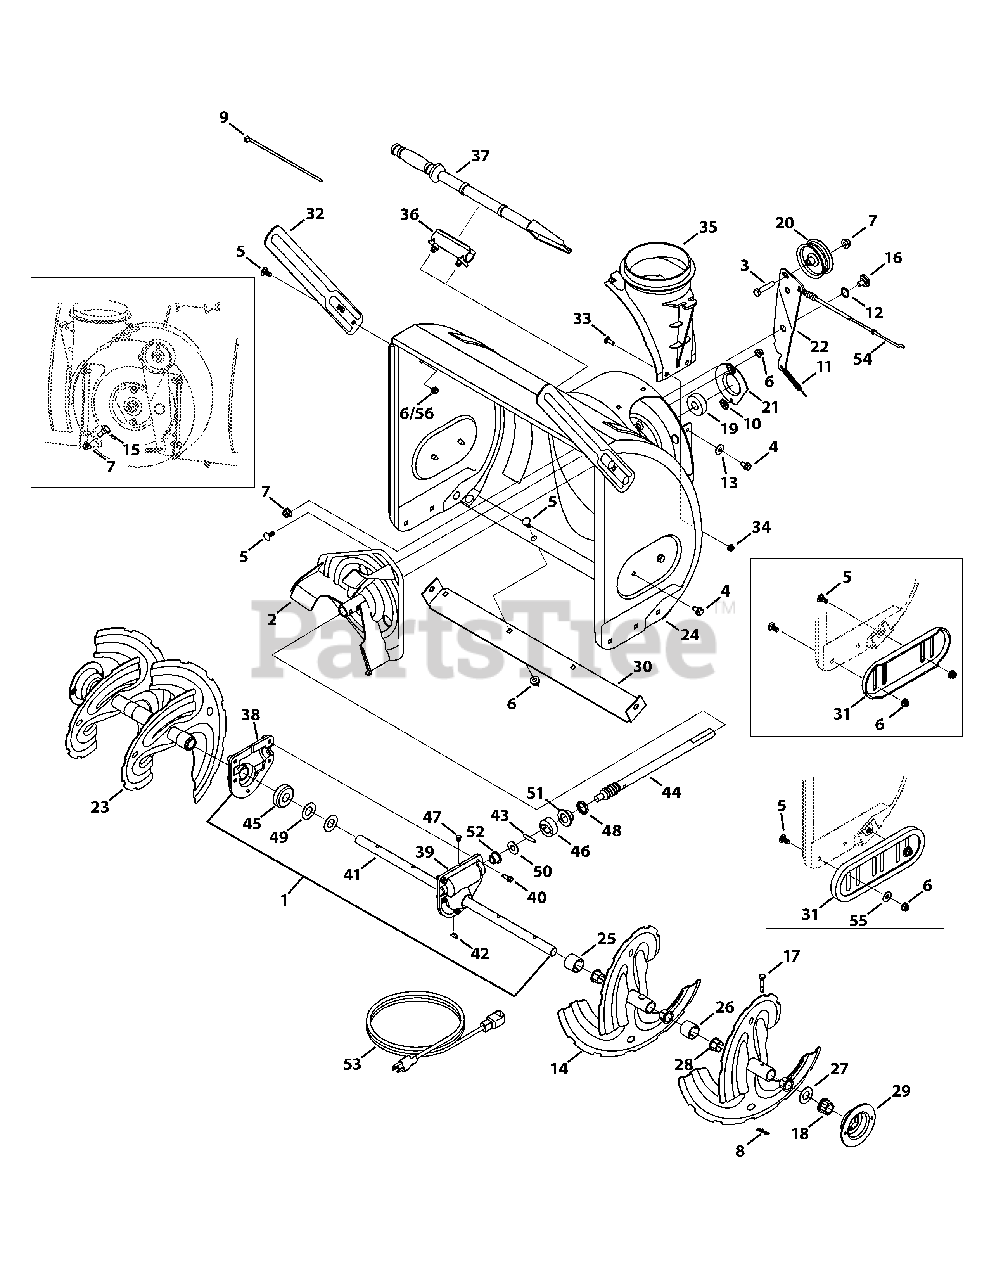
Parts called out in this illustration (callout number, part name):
1	Auger Gearbox 30", includes 38-52
1	Auger Gearbox 28", includes 38-52
1	Auger Gearbox 26", includes 38-52
1	Auger Gearbox 24", includes 38-52
2	Impeller Assembly, 12" Dia.
3	Hex Head Screw, 3/8-16 x 1.75
4	Screw, 5/16-18 x .750
5	Screw, Carriage, 5/16-18 x 1.00
6	Nut, Flange lock, 5/16-18
7	Nut, Flange lock, 3/8-16
8	Bow-Tie Cotter Pin
9	Cable Tie, 7"
10	Nut, Push-on, .25 Dia.
11	Extension Spring, .38 x 4.59
12	Washer, Wave, .625 x .885
13	Washer, Bell, .340 x .872
14	Spiral Assembly, LH - Black
14	Spiral Assembly, LH Gray
15	Bolt, Shoulder, .496 x .336 x 3/8-16
16	Screw, Shoulder, .625 x .17 x 3/8-16
17	Shear Pin, .25 x 1.50
18	Bearing, Hex Flange, .75
19	Bearing, Ball, .75 x 1.85
20	Pulley, Idler, Flat, 2.75
21	Bearing, 1.85 ID
22	Auger Idler Bracket
23	Spiral Assembly, RH - Black
23	Spiral Assembly, RH Gray
24	Auger Housing Assembly
24	Auger Housing Ass'y, 30"
24	Auger Housing Ass'y, 28"
24	Auger Housing Ass'y, 26"
24	Auger Housing Ass'y, 24"
25	Spacer, 1.25 x .75 x 1.00
26	Spacer, 1.25 x .75 x 2.00
27	Washer, Flat, .76 x 1.49
28	Bushing, Flange, .800 x .910
30	Shave Plate, 2.25 x 29.66 (30") Orange
30	Shave Plate, 2.25 x 29.66 (30") Black
30	Shave Plate, 2.25 x 27.66 (28") Orange
30	Shave Plate, 2.25 x 25.66 (26") Orange
30	Shave Plate, 2.25 x 23.66 (24") Orange
31	Reversible Slide Shoe (Steel) Black
31	Reversible Slide Shoe (Steel) Orange
31	Deluxe Polymer Reversible Slide Shoe
31	Deluxe Polymer Reversible Shoe Kit
33	Screw, Carriage, 1/4-20 x .75
34	Nut, Flange lock, 1/4-20
35	Chute Adapter
36	Clean-Out Tool Mount
37	Clean-Out Tool
38	Reducer, RH
39	Reducer, LH
40	Screw, 1/4-20 x 0.750
41	Auger Axle, 30"
41	Auger Axle, 28"
41	Auger Axle, 26"
41	Auger Axle, 24"
42	Key, Hi-Pro, 3/16 x 5/8
43	Dowel Pin, .25 x 1.25
44	Worm Shaft, .75
45	Gear Worm, 20T
46	Collar Thrust, .756 x .600
47	Plug, 1/4 x .437
48	Oil Seal, .75 x 1.131 x .188
49	Washer, Flat, .760 x 1.50
50	Washer, Flat, .51 x 1.12
51	Bearing, Flange, .75 x 1.00 x .59
52	Bearing, Flange, .50 x .75 x .59
53	Extension Cord, 110V
54	Auger Drive Clutch Cable
55	Washer, Flat, .349 x .879 x .063
56	Wing Knob, 5/16-18
